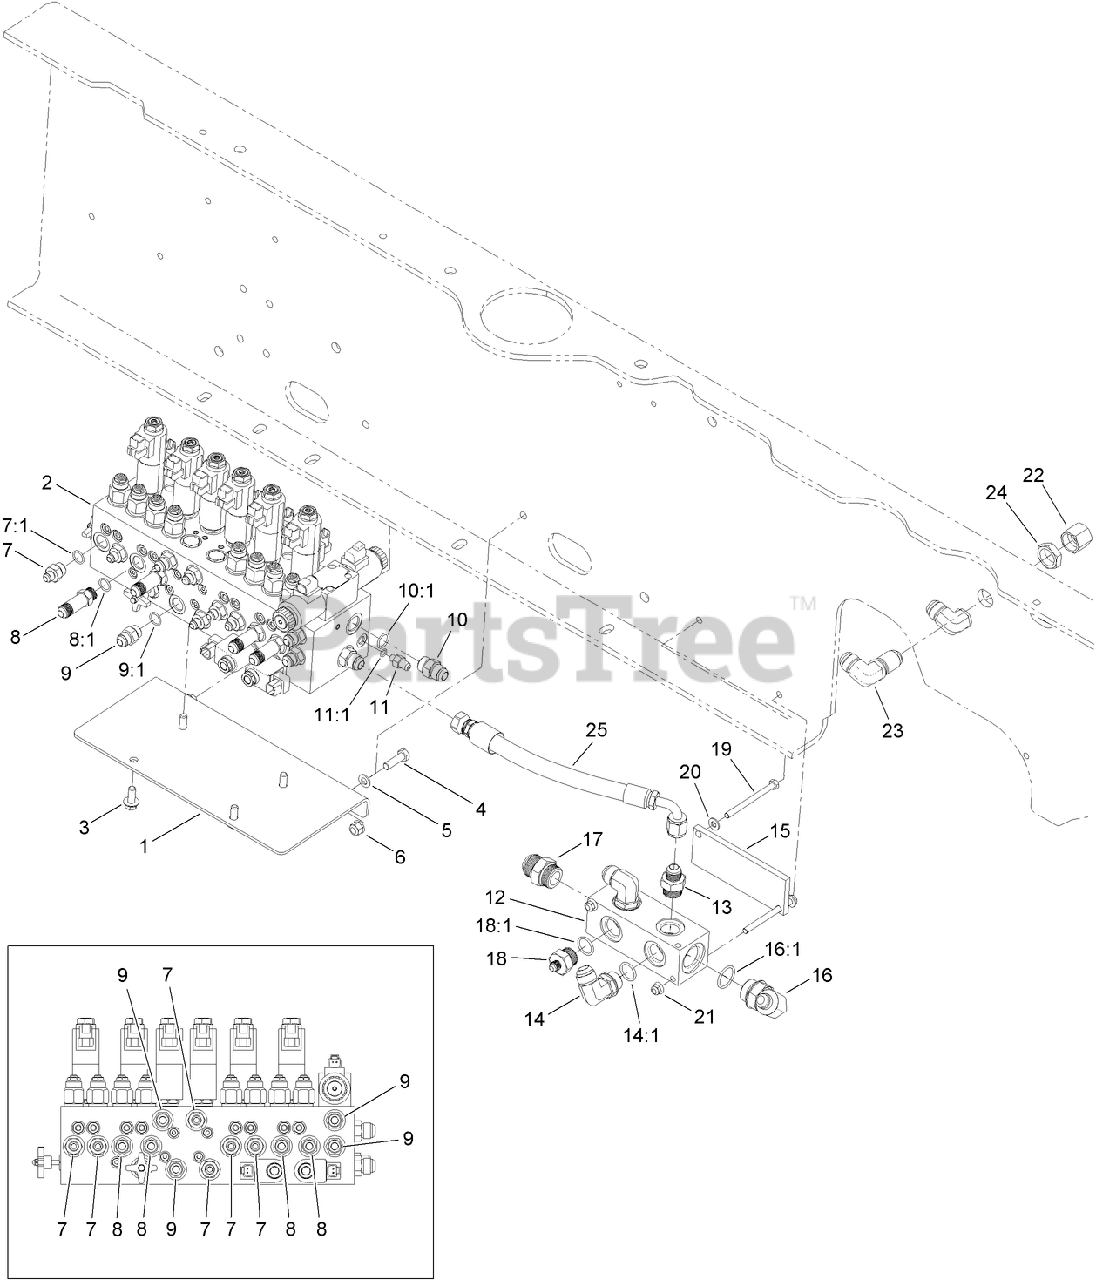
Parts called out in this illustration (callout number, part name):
1	PLATE-MOUNT, FILTER
2	MAIN VALVE ASM
3	SCREW-HHF
4	Screw-HH
5	WASHER-FLAT
6	NUT-LOCK, NI
7	CONNECTOR
7:1	O-RING
8	FITTING-STRAIGHT, LONG
8:1	O-RING
9	FITTING-STRAIGHT
9:1	O-RING
10	FITTING-STRAIGHT
10:1	O-RING
11	ADAPTER-STRAIGHT
11:1	O-RING
12	MANIFOLD ASM (HYD RETURN)
13	FITTING-STRAIGHT
14	FITTING-ELBOW, 90 DEG
14:1	O-RING
16	ELBOW-90, ADJ
16:1	O-RING
17	FITTING-STRAIGHT
18	ADAPTER-STRAIGHT
18:1	O-RING
19	SCREW-HH
20	WASHER-PLAIN
21	NUT-LOCK, HHF
23	FITTING-ELBOW, 90
24	NUT-LOCK, BULKHEAD
25	HYD HOSE ASM, HP
